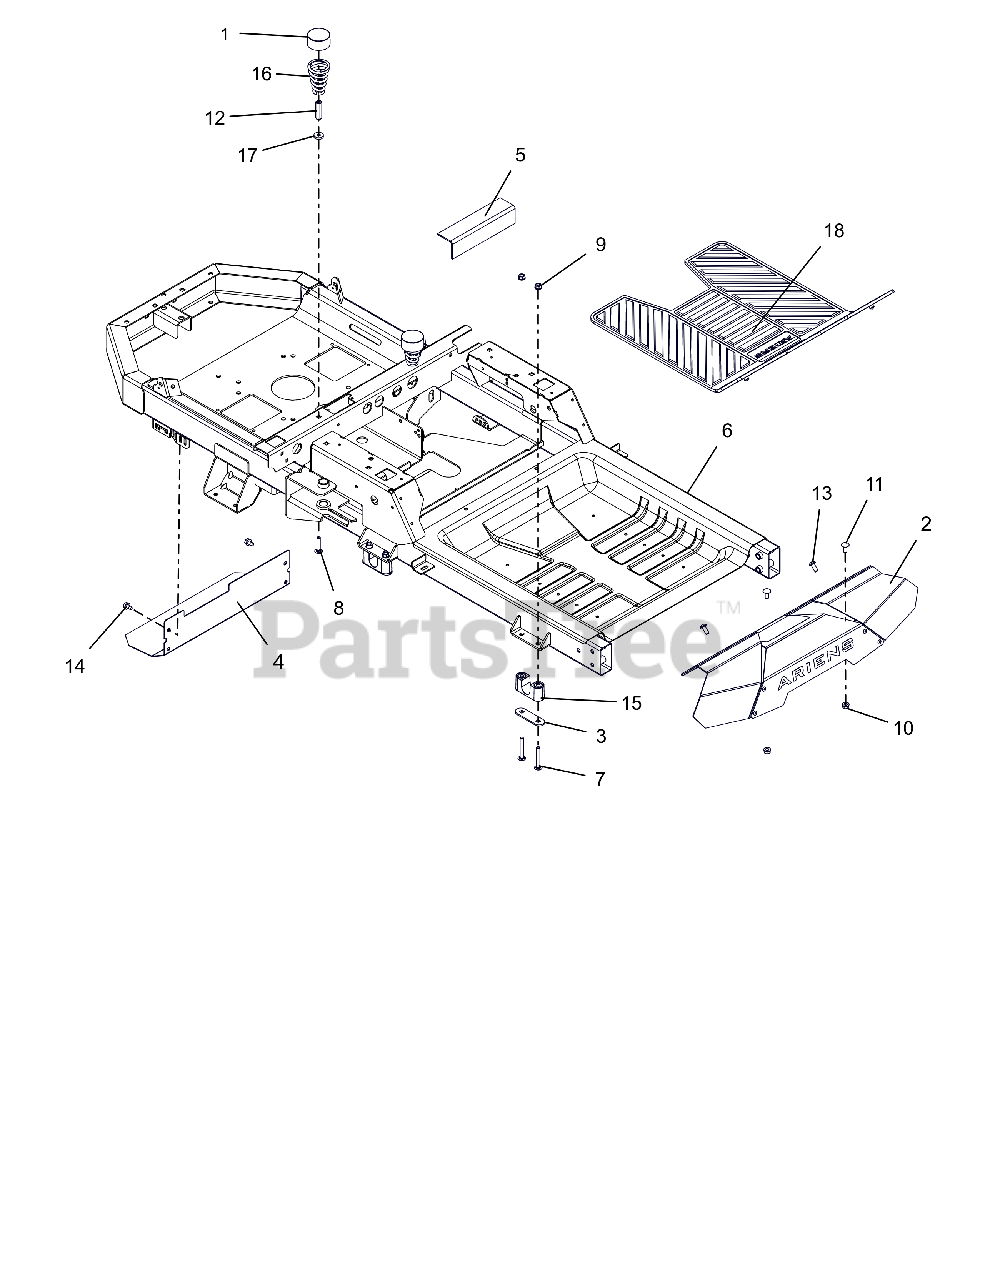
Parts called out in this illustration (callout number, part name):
1	HUB CAP
2	KIT, IKON FOOT REST W/DECAL
3	PLATE, BEARING SUPPORT
4	HEAT, SHIELD
5	PAD, RUBBER-TANK
6	KIT, IKON-X/XL FRAME (2016)
7	BLT-RDHDSQSHNK .31-18X2.25 YWZ
8	BLT,RHSN .31-18X1.50 G5 ZCC
9	NUT,LK-CTR-FLG .31-18 GF ZCC
10	NUT-LK-TOP-FLG .312-18 GF ZCC
11	BLT,RHSN .31-18X.75 G5 ZCC
12	NUT, COUPLING 5/16-18 X 1 3/4
13	SCR-RDHDSKTAP .31-18 X .75
14	SCR,TAP .312-18X.50 HWH TR ZCC
15	BSHG, DECK LIFT PIVOT
16	SPRING, SEAT
17	WSHR, FLT .328X.870X.179 ZCC
18	FLOOR MAT, RUBBER-ARIENS XL
